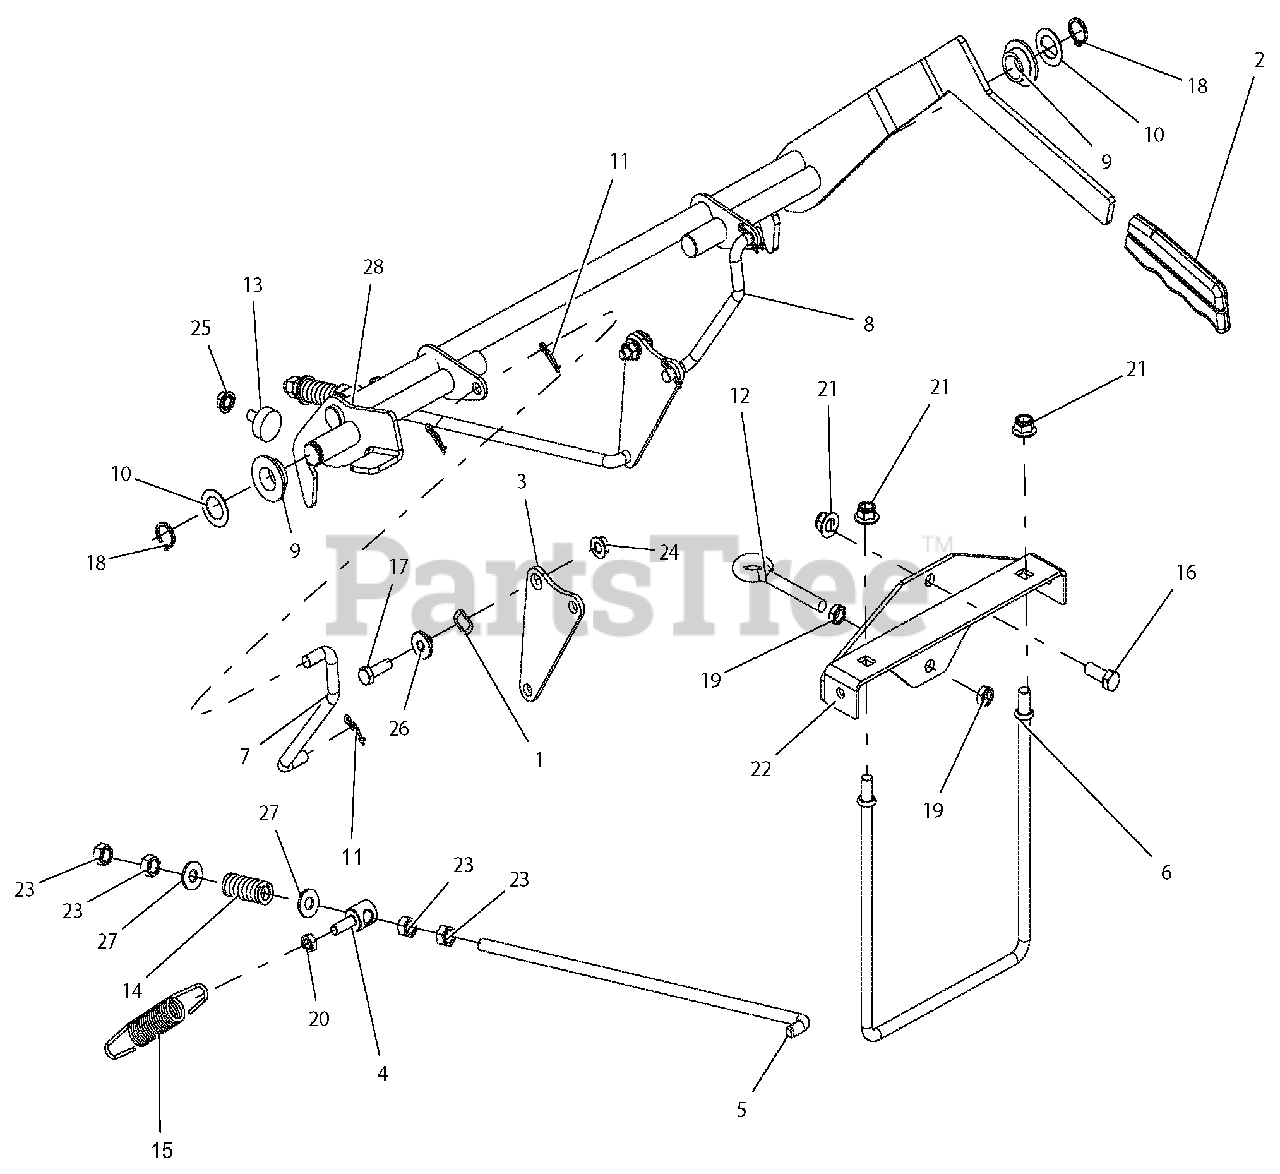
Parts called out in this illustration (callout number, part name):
1	WAVE WASHER .531X.781X.125 FH
2	GRIP, PARKING BRAKE (YELLOW)
3	PLATE, BRAKE PIVOT-BLACK
4	TRUNNION, .31-18
5	ROD, BRAKE ADJ.
6	ROD, BRAKE MTG
7	LINKAGE, RH BRAKE ACTUATING
8	LINKAGE, LH BRAKE ACTUATING
9	BSHG, FLANGE .762 X 1.48 X .44 NYLON
10	WSHR-HDND-THRST
11	PIN-HAIR, ENDRIES #25 YWZC
12	BOLT, EYE .375-16
13	BUMPER, RUBBER
14	SPRG, COMPRESSION
15	SPRG, TENSION .105 X .850 X 4.880
16	BLT-HEX .38-16X1.00 GR5 YWZC
17	BLT-HEX .31-18X1.00 GR5 YWZC
18	RG-RTNG-EXT .750x.078
19	NUT, JAM .375-16 YWZC
20	@NUT-LK-CTR-JAM .31-18 YWZC
21	NUT-LK-NYL-FLG .38-16 YWZC
22	WMT, SPRING ANCHOR BRKT-BLACK
23	NUT-HEX .38-16 YWZC
24	NUT, LK-TOP-FLG .312-18 YWZC
25	@NUT-SPNLK-FLG .312-18 YWZC
26	BSHG, FLG .32X.500.344X.880
27	WSHR-FL-STL.38X.875X.083 YWZC
28	WLDMT, PARKING BRAKE LEVER
